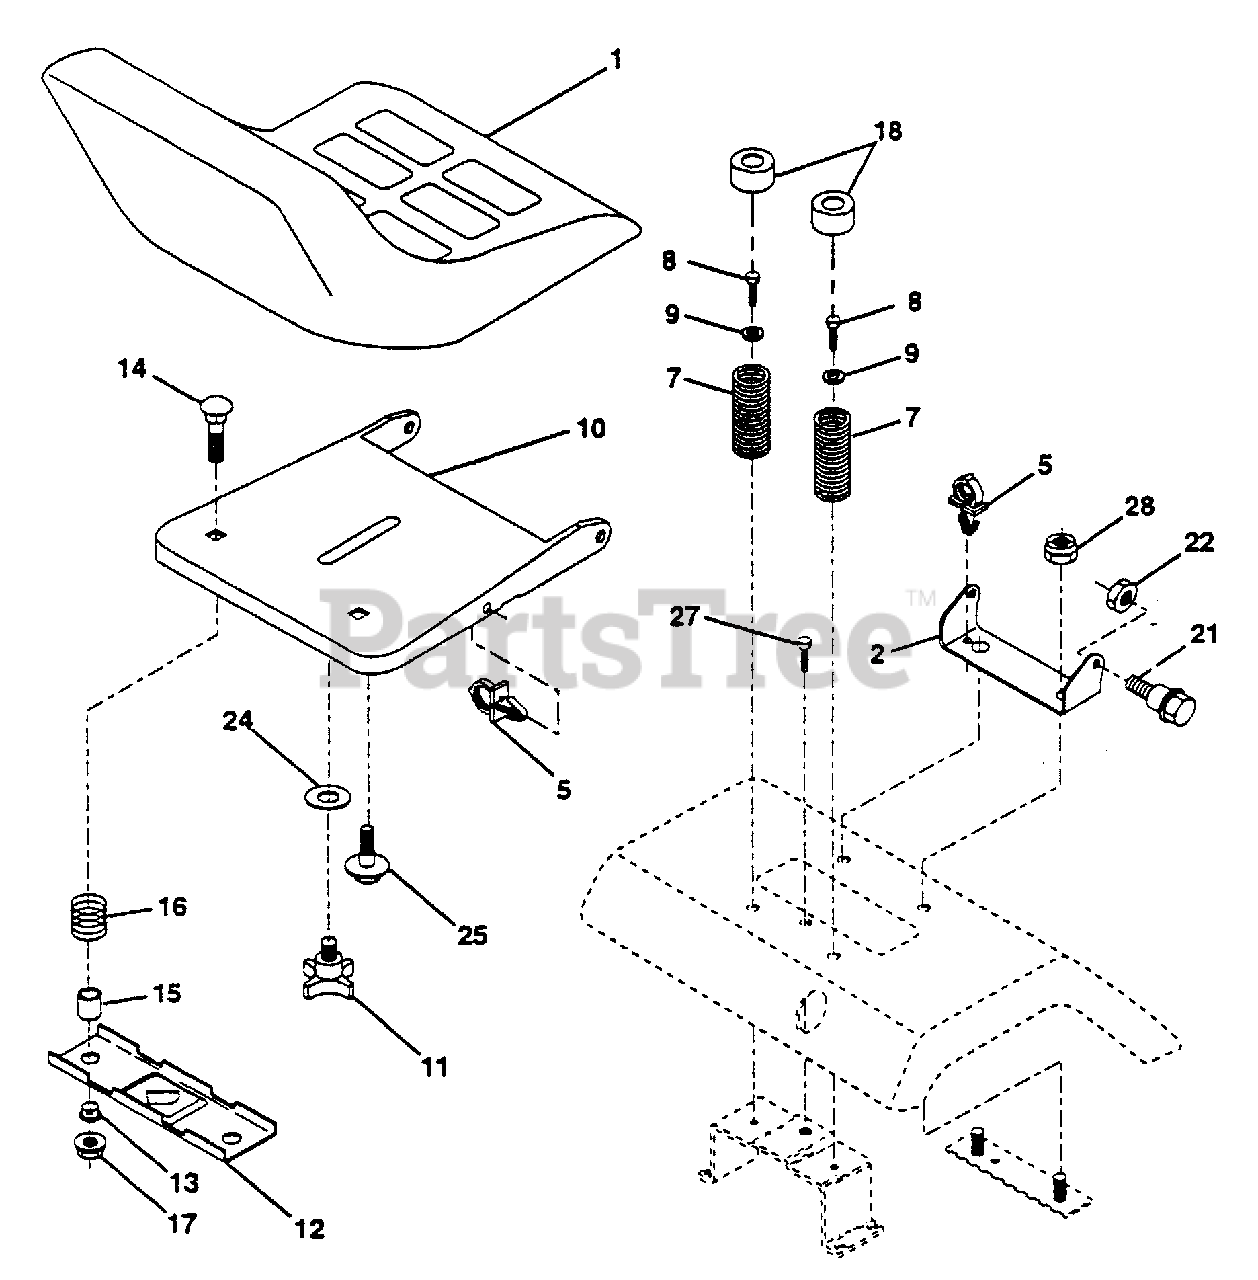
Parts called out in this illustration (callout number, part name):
1	Seat V-550 Gry/blk Std
2	Bracket Pivot Seat
5	Clip, Push-In Hinged
7	Spring Seat Cprsn 2 250 Blk Zi
8	Screw Hwsh Thdrol 5/16-18 x 1/2
9	Washer 13/32 X 1 X 14 Ga
10	Pan Seat
11	Knob Seat 1/2-13unc Blk
12	Bracket Mounting Switch
13	Bushing Snap Blk Nyl 50 Id
14	Bolt Rdhd Sht Nk 1/4-20x1-3/8
15	Spacer Split 28x 88 Yel Zinc
16	Spring Cprsn 1 310 Blk Pnt
17	Nut Lock 1/4 Lge Flg Gr 5 Zinc
18	Cap Spring Seat
21	Bolt Shoulder 5/16-18 Unc Blkz
22	Nut Crown Lock 5/16-18
24	Washer 17/32 X 1-3/16 X 12 Ga
25	Bolt Shoulder 5/16-18 X 62
27	Screw Thdrol 3/8-36 x 1/2
28	Nut Crownlock 3/8-16 UNC
